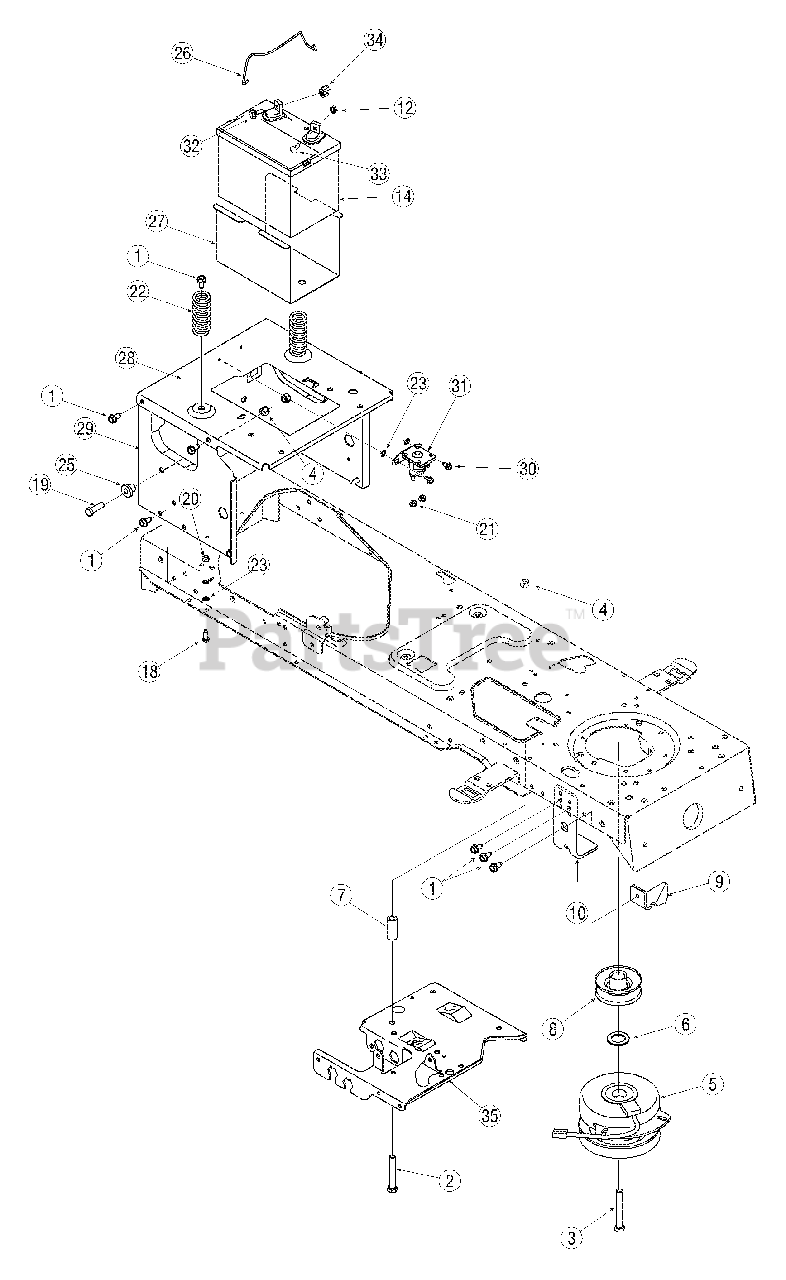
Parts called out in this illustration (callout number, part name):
1	Screw, 5/16-12, 0.75
2	Screw, 3/8-16, 2.50, Gr5
3	Screw, 7/16-20, 3.25, Gr5, Lock
4	Nut, Flange Lock, 3/8-16, Gr F, Nylon
5	PTO Clutch, Electric
6	Washer, Flat, 1.031 x 1.620 x.095
7	Spacer, .385 ID x .635 OD x 1.54
8	Pulley, Engine, 3.56 Diameter
11	Screw, Carriage, 1/4-20, .75, Gr5
12	Nut, Sems, 1/4-20
13	Nut, Wing, 1/4-20
14	Battery, 235 CCA
15	Screw, Shoulder, .250 x .150, 1/4-20
18	Screw, 1/4-20, 0.750
19	Screw, 3/8-16, 1.25, Gr5
20	Nut, Flange Lock, 1/4-20, Gr F, Nylon
21	Nut, Hex, 1/4-20, Gr5
22	Spring, Compression, 1.28 OD x 3.125
23	Washer, Lock, 1/4, External
24	Washer, Lock, 1/4
25	Spacer, Shoulder, .38 x 1.0 x .70
26	Hold Rod, Battery
31	Solenoid, 12V, 100 Amp
32	Screw, Shoulder, .250 x .15, 1/4-20
33	Screw, Carriage, 1/4-20, .75
34	Nut, Wing, 1/4-20
